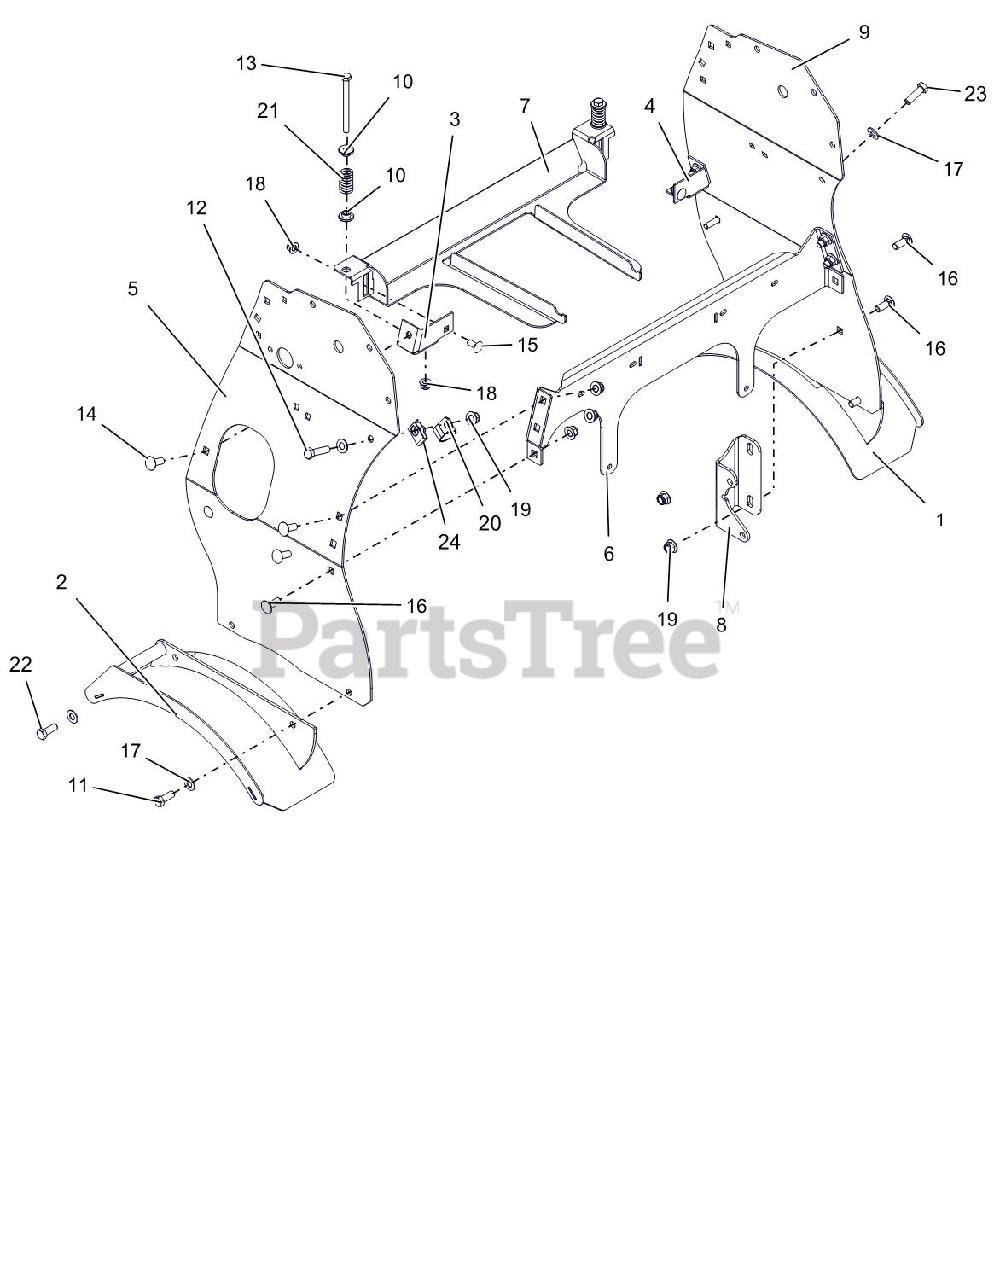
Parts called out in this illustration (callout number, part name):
1	BRKT, LH FENDER
2	BRKT, RH FENDER
3	MOUNT, FUEL TANK HOLD DOWN-RH
4	MOUNT, FUEL TANK HOLD DOWN-LH
5	KIT, SERVICE RH TOWER & DECAL
6	BRKT, CONTROL TOWER STIFFENER
7	HOLDDOWN, FUEL TANK
8	BRKT, TOWER SUPPORT
9	SIDE, LH PROSTANCE TOWER
10	BSHG-FLG .32X.500X.344X.880
11	@BLT-HEX .38-16X1.00 GR5 YWZC
12	@BLT-HEX .38-16X1.50 GR5 YWZC
13	BLT-HEX .312-18X3.75 YWZC
14	@BLT-RDHDSHSQNK.38-16X1.0 G5YZ
15	@BLT-RDHDSQNK .31-18X.75 G5YZ
16	@BLT-RDHDSQNK .38-16X1.00 G5YZ
17	@WSHR-FL-STL.406X.812X.065 YWZ
18	@NUT-LK-NYL-FLG .31-18 YWZC
19	@NUT-LK-NYL-FLG .38-16 YWZC
20	CLAMP, COUSHIONED STEEL REV
21	SG-COMP .125X.781X1.250
22	@BLT-HEX .38-16X1.00 GR5 YWZC
23	@BLT-HEX .38-16X1.25 GR5 YWZC
24	NUT-RTNR .375-16X.37
